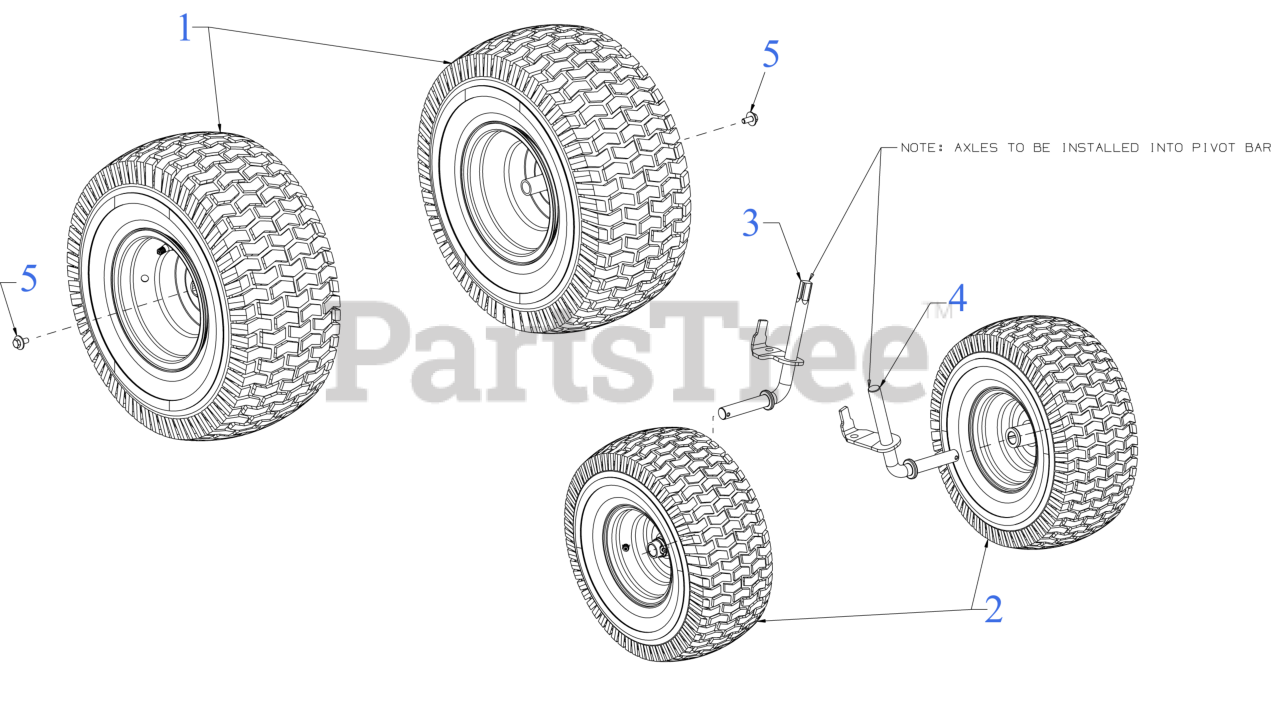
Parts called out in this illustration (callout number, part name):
3	AXLE ASSEMBLY, (RH)
4	FRONT AXLE ASSEMBLY(LH)
5	SCREW 5/16-24 x .750 GR5
